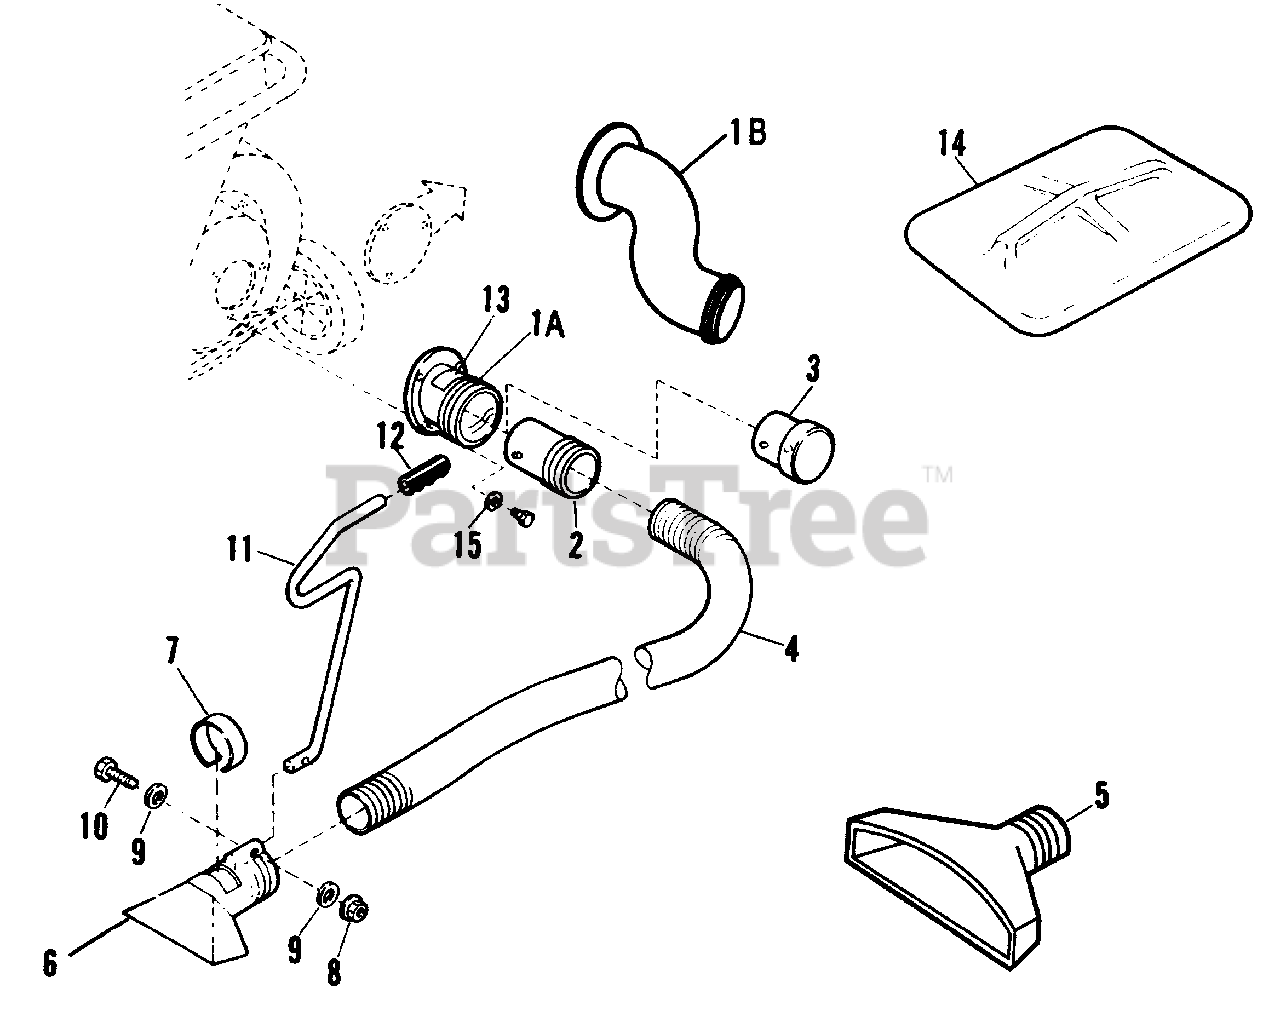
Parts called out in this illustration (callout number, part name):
1B	ADAPTER (European model only)
4	HOSE, 10" x 4" Dia.
6	NOZZLE, w/Valve Ring
7	VALVE RING, Notched, 5" Dia. x 3" Long
8	NUT, 1/4-20
9	WASHER, 1/4
10	SCREW, 1/4-20 x 1 1/2
11	HANDLE
12	HANDLE GRIP
13	DECAL, Danger
14	HOPPER LID (Orange)
14	HOPPER LID (Gold)
14	HOPPER LID (Red)
15	WASHER, Flat
